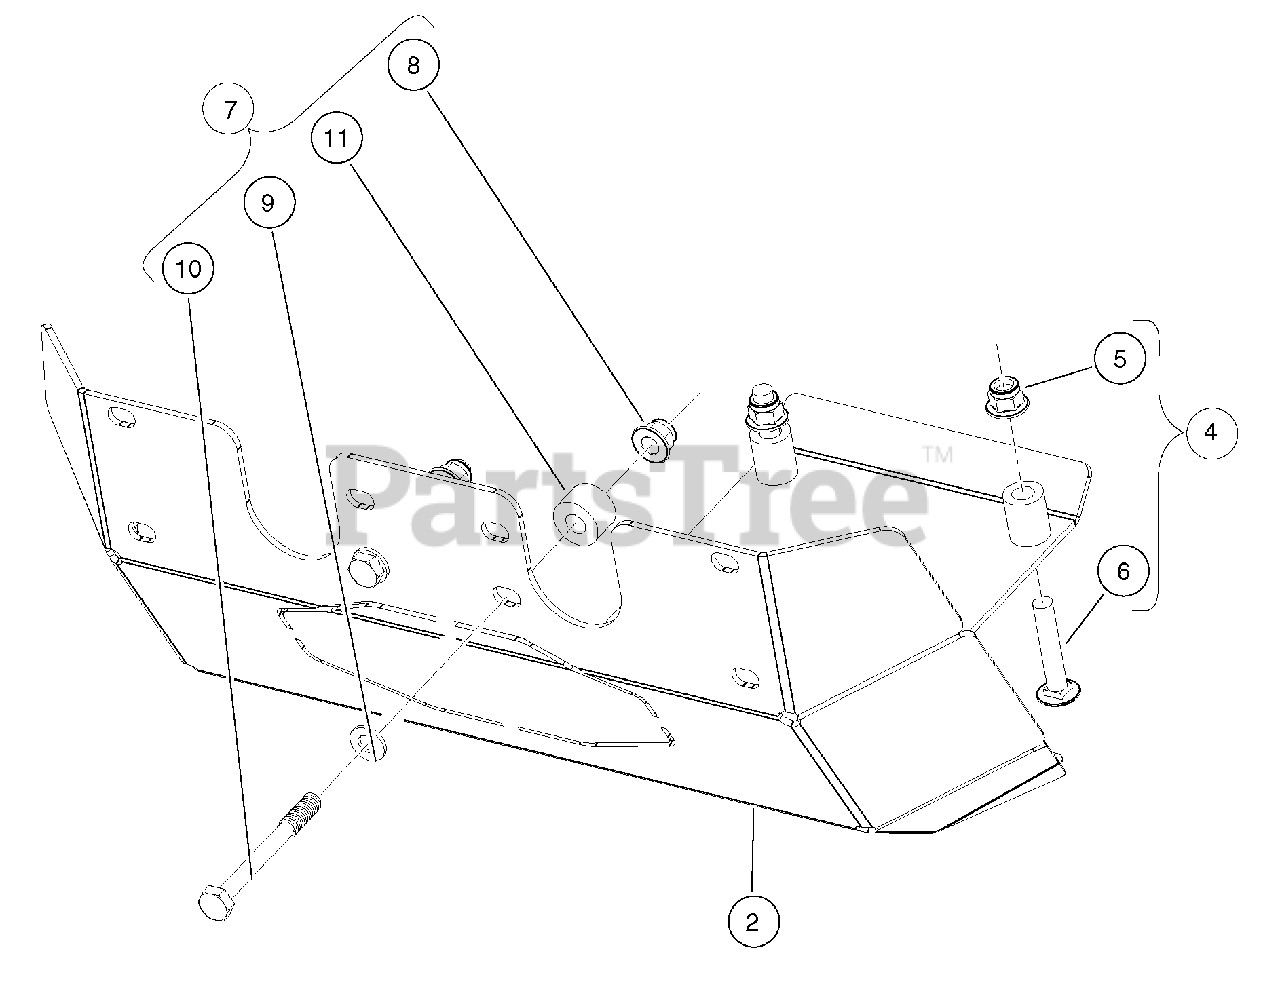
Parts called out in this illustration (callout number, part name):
1	Kit, Skidplate, Front, Steel
2	Skid Plate, Front, Steel
3	Instructions, Front Skidplate
4	Kit, Hardware, Skidplate, Front, A
5	Nut Flg M10 X 1.5 Nylon
6	Bolt, Carriage, M10x1.5x55
7	Kit, Hardware, Skidplate, Front, B
8	Nut Flg M10 X 1.5 Nylon
9	Washer, Hard, M10, Zn-Ni/Blk
10	Bolt, M10 X 1.50 X 90, Loctite
11	Spacer, 17mm Long, Skidplate
